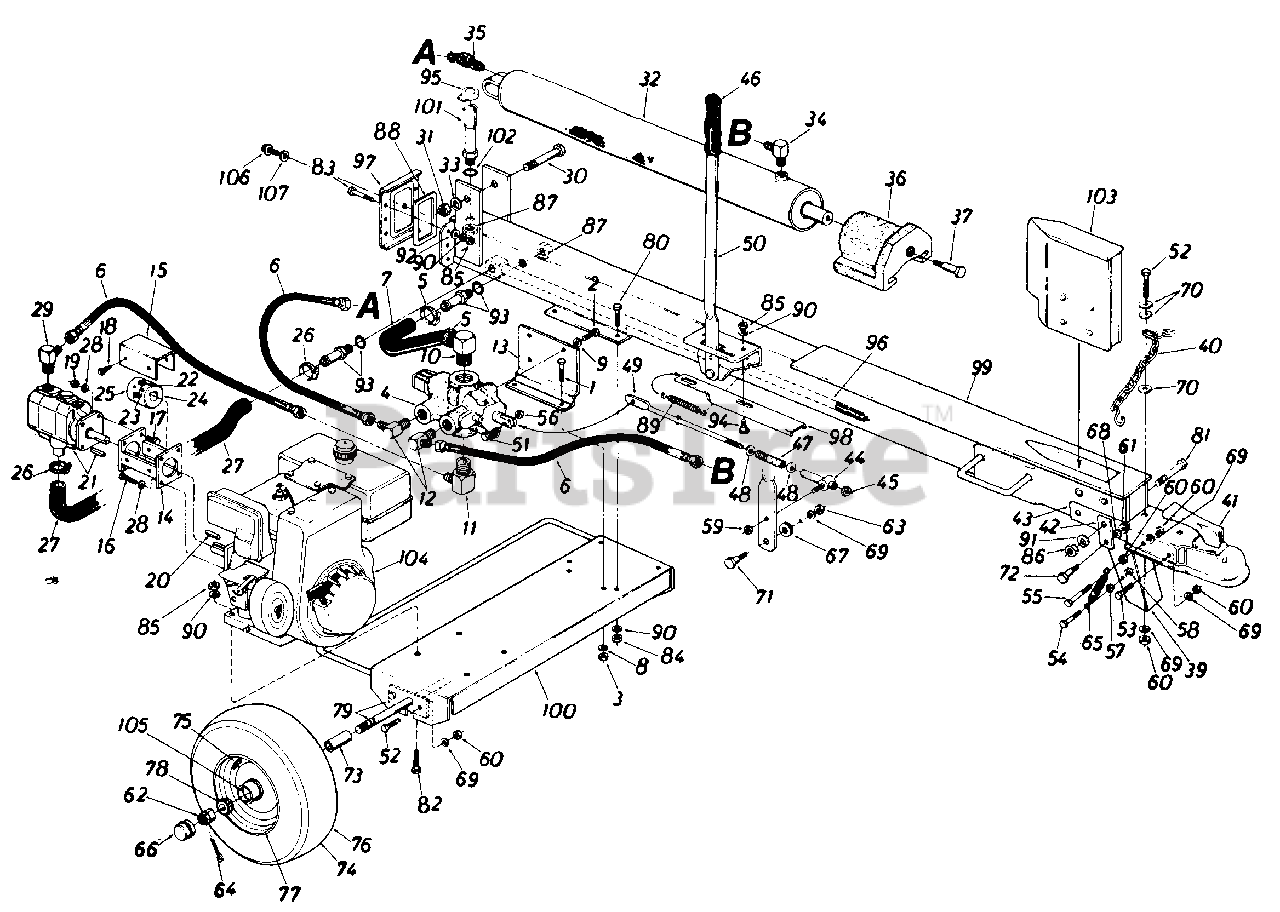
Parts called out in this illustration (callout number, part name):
1	SCREW-HEX 5/16-18 X .75
2	SCREW-HEX 3/8-16 X .50
3	NUT-HEX 5/16-18
4	VALVE-CONTROL
5	CLAMP-HOSE-5/8
6	HOSE ASSY-PRESSURE
7	HOSE-RETURN
8	WASHER-LOCK-5/16
9	WASHER-LOCK-3/8
10	ELBOW-RETURN
11	ADAPTER-90 DEGREE
12	ADAPTER-90 DEGREE
13	PLATE-MTG-VALVE
14	BRACKET-COUPLING SUP
15	SHIELD-COUPLING
16	SCREW-HEX SPECIAL 5/16-24X1.0
17	SCREW-HEX 5/16-24 X .75
18	SCREW-TAP 1/4-20 X .38
19	NUT-5/16-24
21	PUMP
22	Spider L-0-90
23	SCREW-SET 1/4-20 X .25 CUP
24	COUPLING HALF
25	COUPLING-HALF
26	CLAMP-HOSE-5/8
27	HOSE ASSY-SUCTION
28	WASHER-LOCK-5/16
29	ADAPTER-90 DEGREE
30	SCREW-HEX 3/4X4.0
31	NUT-HEX 3/4
32	CYLINDER-HYDRO
33	WASHER
34	ADAPTER-90 DEGREE
36	PLATE-PUSH
37	SCREW-SHLD .62X.475
39	BRACKET-FLIP STAND
40	CHAIN-TOW HITCH
41	HITCH ASSY-TOW
42	BRACKET-PIVOT
43	BRACKET-TOW HITCH
44	FERRULE ASSY
45	NUT-HEX INS L 3/8 X 24
46	GRIP-LIFT HANDLE
47	SPRING-BRAKE
48	WASHER-SPEC .378 X 1.00 X .125
49	ROD-ENGAGEMENT
50	HANDLE-ENGAGEMENT
51	SCREW-HEX 1/4-20 X 1.25
52	BOLT-3/8 NF X 1"GR5
53	SCREW-HEX 3/8-24 X .75
54	SCREW-HEX 1/4-28 X 1.00
55	SCREW-HEX 3/8-24 X 1.75
56	NUT-HEX CENTER L-1/4-20
57	NUT-HEX CENTER L-1/4-28
58	NUT-HEX 1/4-28
59	NUT-HEX CENTER L-5/16-18
60	NUT-HEX 3/8-24
61	NUT-HEX 5/16-18
62	NUT-HEX CASTLE
63	NUT-HEX 3/8-16
64	PIN-COTTER-5/32 DIA
65	SPRING-EXTENSION
67	WASHER-RUBBER .50 X 1.00 X .25
68	WASHER-LOCK-5/16
69	WASHER-LOCK-3/8
70	WASHER-FL-.385 ID X .87 OD X .06
71	SCREW-SHLD .498 DIA X .340
72	SCREW-SHLD .437 DIA X .265
75	VALVE-TUBELESS AIR
76	TIRE-PNEU 16.0X4.0
78	BEARING-ROLLER-3/4 IN
79	AXLE ASSY
80	SCREW-HEX SPECIAL 5/16-24X1.0
81	SCREW-HEX 5/8-18 X 3.50
82	SCREW-HEX 5/16-24 X 1.75
83	SCREW-HEX 5/16-18 X 1.50
84	NUT-5/16-24
85	NUT-HEX 5/16-18
86	NUT-HEX 5/8-18
87	NUT-HEX 1 1/16-12
89	SPRING-EXTENSION
90	WASHER-LOCK-5/16
91	WASHER-LOCK-5/8
92	WASHER-FL (#46041)
94	SCREW-SHLD .437 DIA X .180
95	CAP ASSY-GAS
96	TUBE ASSY-STRAINER
97	PLATE-END
98	BRACKET-ENGAGE
99	TANK ASSY
100	FRAME ASSY
101	TUBE ASSY-FILLER
103	WEDGE ASSY
105	RETAINER-GREASE
106	SCREW-HEX WASH HD 5/16-18
107	WASHER-GASKET
